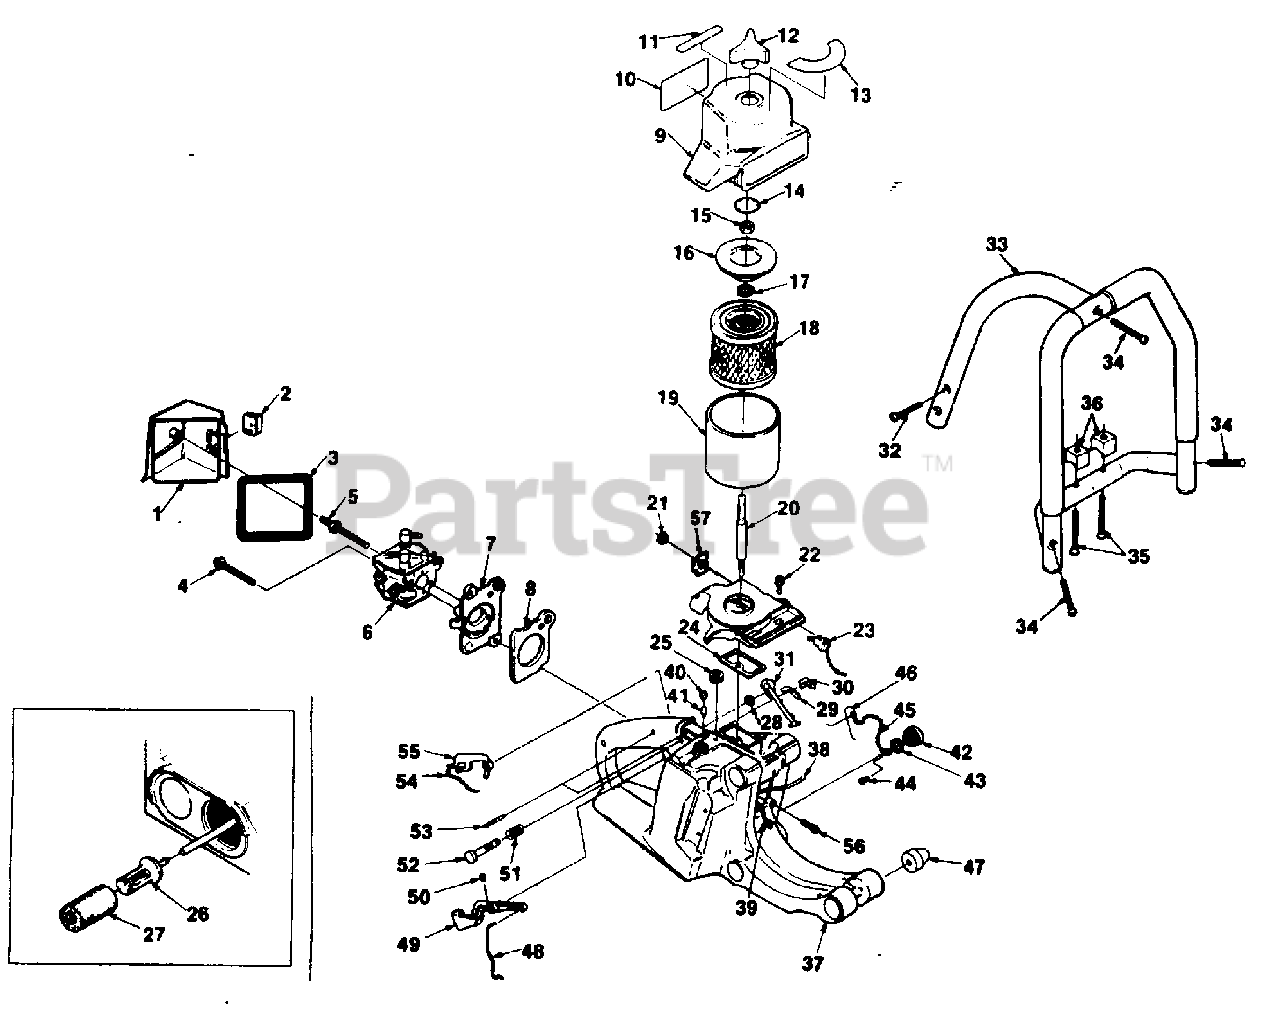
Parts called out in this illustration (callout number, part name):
1	COVER- Carburetor chamber
2	GROMMET- Hi-Lo
3	GASKET- Carburetor cover
4	SCREW- Hex sems hd.
5	STUD- Shoulder
6	CARBURETOR (WS-22) Walbro
7	ADAPTOR- Carburetor
8	GASKET- Carburetor adaptor
9	COVER- Filter
12	KNOB
14	RING- Retaining
15	NUT- Hex 5/16-18
16	COVER- Filter element
18	ELEMENT- Air filter
19	FOAM- Air filter
20	STUD- Threaded
21	NUT- Hex
22	SCREW
23	SWITCH & LEAD
25	GROMMET & "O" RING ASSEMBLY
26	FUEL FILTER
27	ELEMENT- Felt filter
28	RING- Retaining
29	RETAINER- Choke
30	SEAL- Choke rod
31	ROD-Choke
32	SCREW- Oval hd.
33	HANDLE BAR
35	SCREW- Mach oval hd.
36	BRACKET- Handle bar
37	HOUSING- Engine
38	TUBING- 8 3/4" (fuel line)
39	TUBING- 4 3/4 (pulse line)
40	FILTER-
41	VALVE- Check
42	CAP- Fuel
43	GASKET- Cap
44	SCREW- Plastic X-slot
45	CHAIN- Bead
46	KEEPER- Cap
47	ISOLATOR
48	ROD- Throttle
49	TRIGGER- Throttle
51	SPRING- Compression
52	PIN- Throttle lock
53	PIN- Trigger
54	SPRING- Flat
55	LOCK- Trigger
56	SCREW- 8-32 x 1/2
57	PLATE- Indicating
